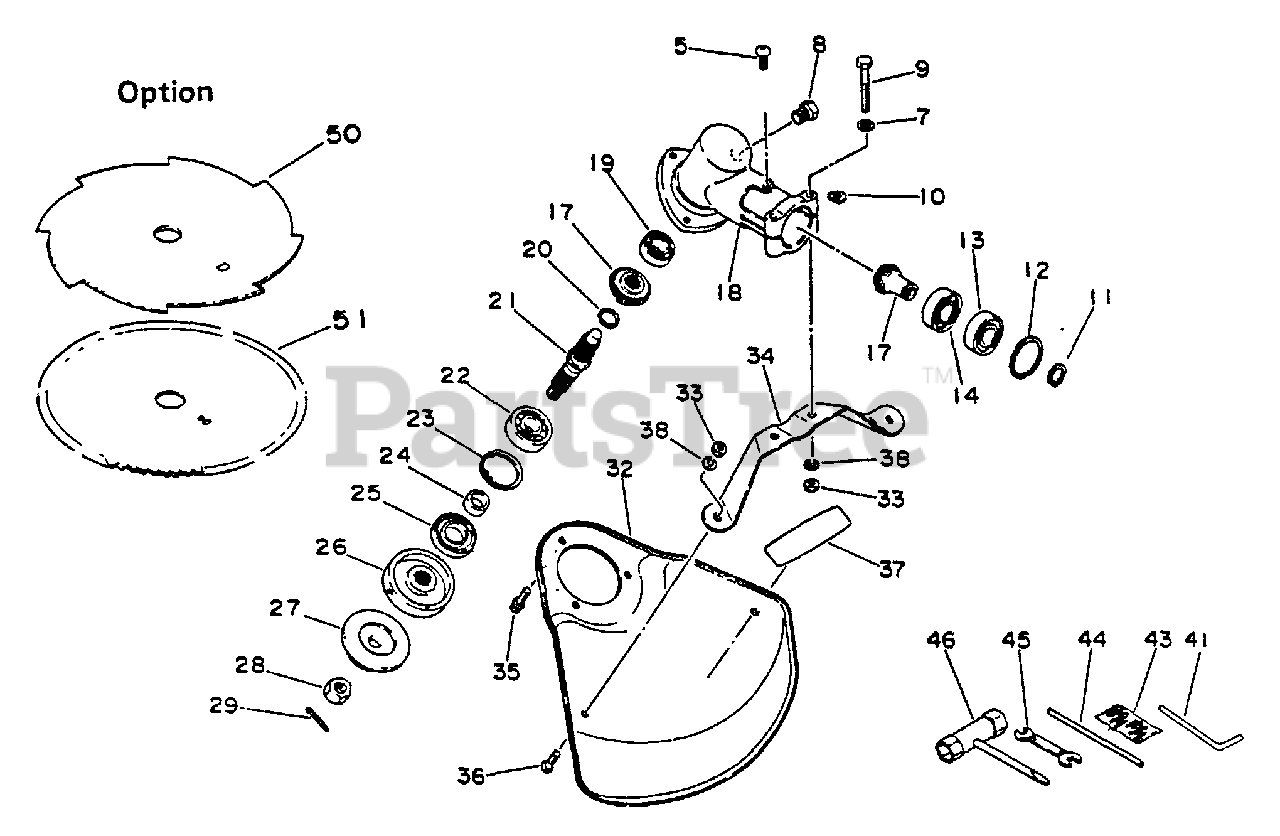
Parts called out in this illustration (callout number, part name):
5	SCREW 5×10
7	WASHER, FLAT 5.5×10×0.8
8	BOLT 8×8 SP
9	BOLT 5×40
11	RING, RETAINING - 12
12	RING, SNAP 28
13	BEARING, BALL 6001
14	BEARING, BALL 6001
17	GEAR SET
18	CASE, GEAR
19	BEARING, BALL 6000
20	RING, RETAINING - 12
21	SHAFT, GEAR
22	BEARING, BALL - 6201 C3
23	RING, SNAP Ø32
24	SPACER 11.8×15×9
25	SEAL, OIL 22
26	PLATE, ADAPTER - UPPER
27	PLATE, ADAPTOR - LOWER
29	PIN, COTTER 2×22
32	SHIELD
33	NUT M5
34	BRACKET, SHIELD
35	SCREW 5×10
36	SCREW 5×8
37	LABEL - ECHO
38	WASHER, SPRING 5
41	WRENCH, ALLEN 4 MM
43	PIN, COTTER 2×22 (PKG. OF 10)
44	TOOL, LOCKING 5×120 MM
45	SPANNER 8×10
46	T-WRENCH
50	BLADE, 25 MM ID - 10"
51	BLADE, 25 MM ID - 8 TOOTH -- 8"
